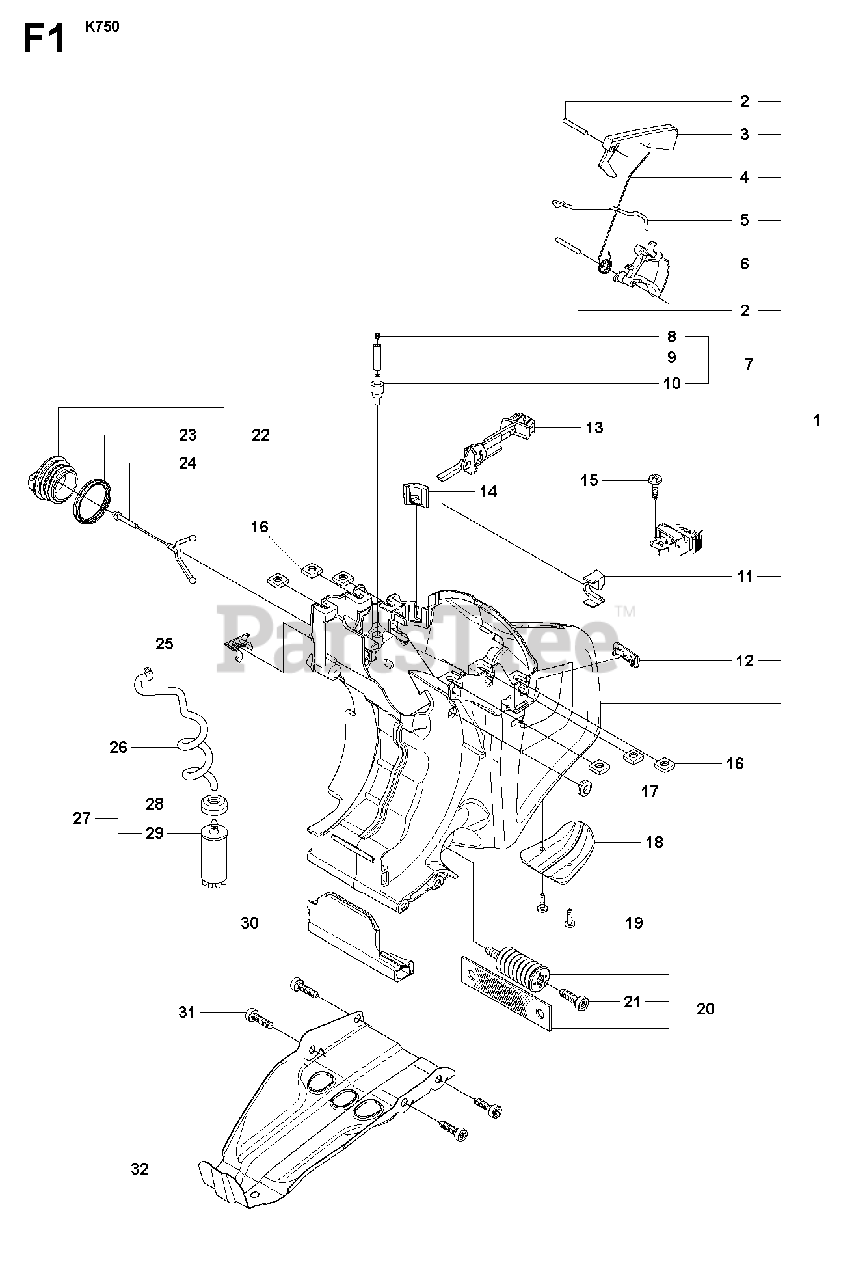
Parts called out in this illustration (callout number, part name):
1	FUEL TANKIncl. 2 - 7, 11, 12
2	PARALLEL PIN
3	THROTTLE LOCKOUT
4	SPRING
5	THROTTLE ROD
6	THROTTLE TRIGGER
7	TANK VENT ASSYIncl. 8 - 10
13	CHOKE CONTROL
15	SCREW CCRPANT
17	CABLE GROMMET
18	GROUND SUPPORT
19	SCREW CRCSFT
20	ANTIVIBRATION ELEMENTIncl. 21
21	SCREW ITXSCM
22	TANK CAP ASSYIncl. 23, 24
25	HUB CAP
26	FUEL HOSE
27	FUEL FILTERIncl. 28, 29
31	SCREW ITXSCT
